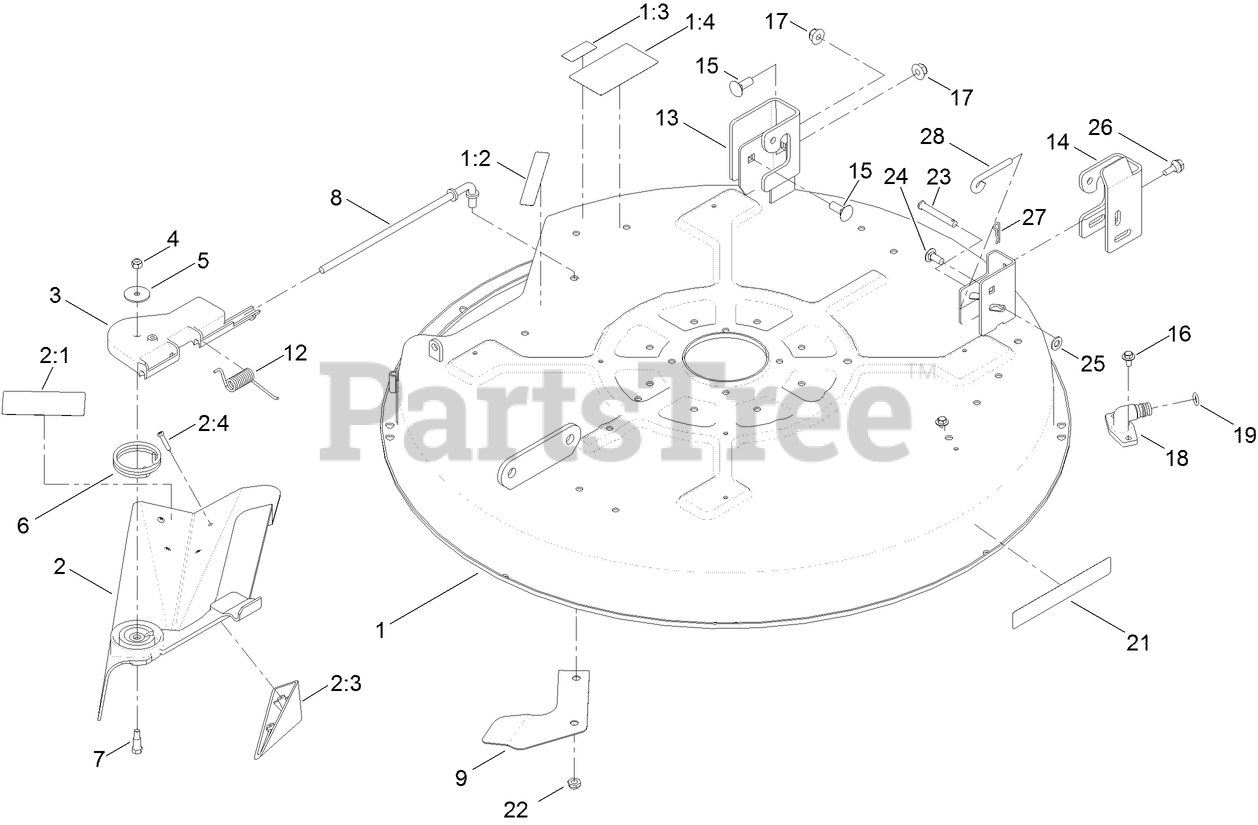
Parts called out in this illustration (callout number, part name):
1	32 INCH DECK AND DECAL ASM
1:2	DECAL-DANGER
1:3	DECAL-DANGER
1:4	DECAL-DANGER
2	32 INCH DEFLECTOR ASM
2:1	DECAL-DANGER
2:3	KICKER
2:4	SCREW-PPH
3	PIVOT-HINGE, DEFLECTOR
4	NUT-LOCK, NI
5	WASHER-FLAT
6	SPRING-TORSION
7	BOLT-SHOULDER
8	ROD-PIVOT
9	RAMP-DEFLECTOR
12	SPRING-TORSION
13	BRACKET-HANGER, RH
14	BRACKET-HANGER, LH
15	BOLT-CARR
16	SCREW-HHFTF
17	NUT-HF, NI
19	O-RING
21	DECAL-RECYCLER
23	PIN-CLEVIS
24	SCREW-CARR
25	WASHER-PLAIN
26	SCREW-SHOULDER,HWH
27	PIN-COTTER
28	ROD-LEVEL, DECK
